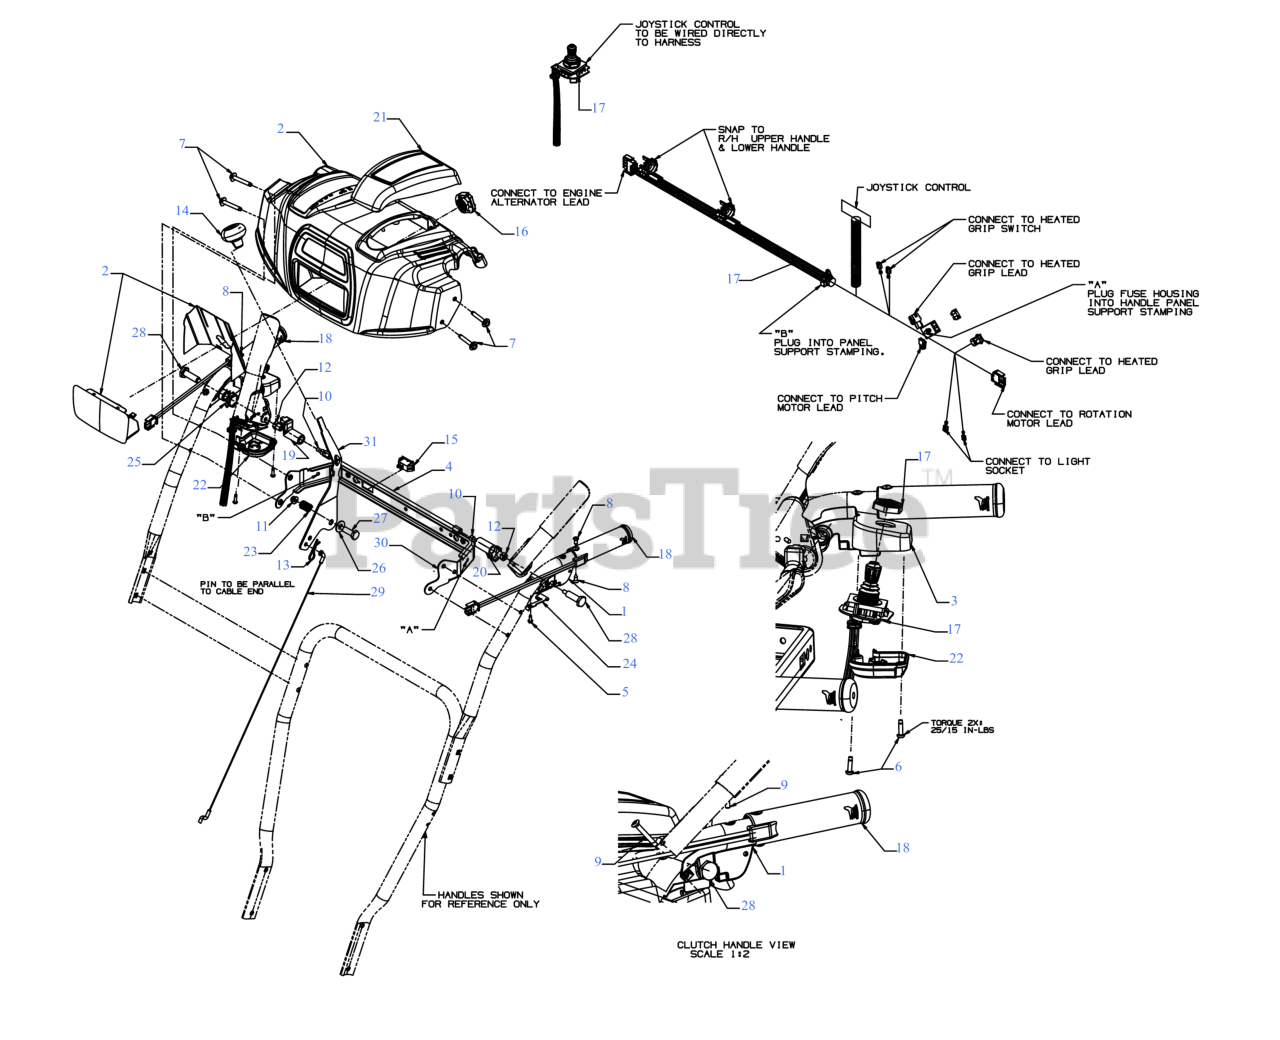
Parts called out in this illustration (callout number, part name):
1	CLUTCH LOCK HANDLE ASSEMBLY (LH)
2	HANDLE PANEL ASSEMBLY
3	CLUTCH HANDLE ASSEMBLY (RH)
4	PIVOT ROD
5	SCREW #8-16 x .50
6	SCREW .159 x .610
7	SCREW 1/4-20 x 1.625
8	SCREW-AB #12-24 x .625
9	SCREW #10-24 x 1.375
10	SCREW 1/4-20 x .50
11	FLANGE LOCK NUT
12	HEX NUT W/PATCH
13	INTERNAL COTTER PIN
14	SHIFT KNOB
15	HEATED GRIP SWITCH
16	LED HEADLIGHT SOCKET (150 LUMNES)
17	4-WAY ELEC/HEAT GRIP HARNESS
18	HEATED GRIP
19	LOCK PLATE
20	CLUTCH LOCK CAM
21	HANDLE COVER PANEL
22	JOYSTICK HOUSING COVER
23	COMPRESSION SPRING
24	CLUTCH SPRING
25	TORSION SPRING
26	FLAT WASHER .40X.88X.060
27	SHOULDER SCREW
28	SHOULDER SCREW .437 x 1.345 1/4-20
29	SPEED SELECTOR CABLE (PLASTIC)
30	HANDLE SUPPORT BRACKET (POWDER BLACK)
